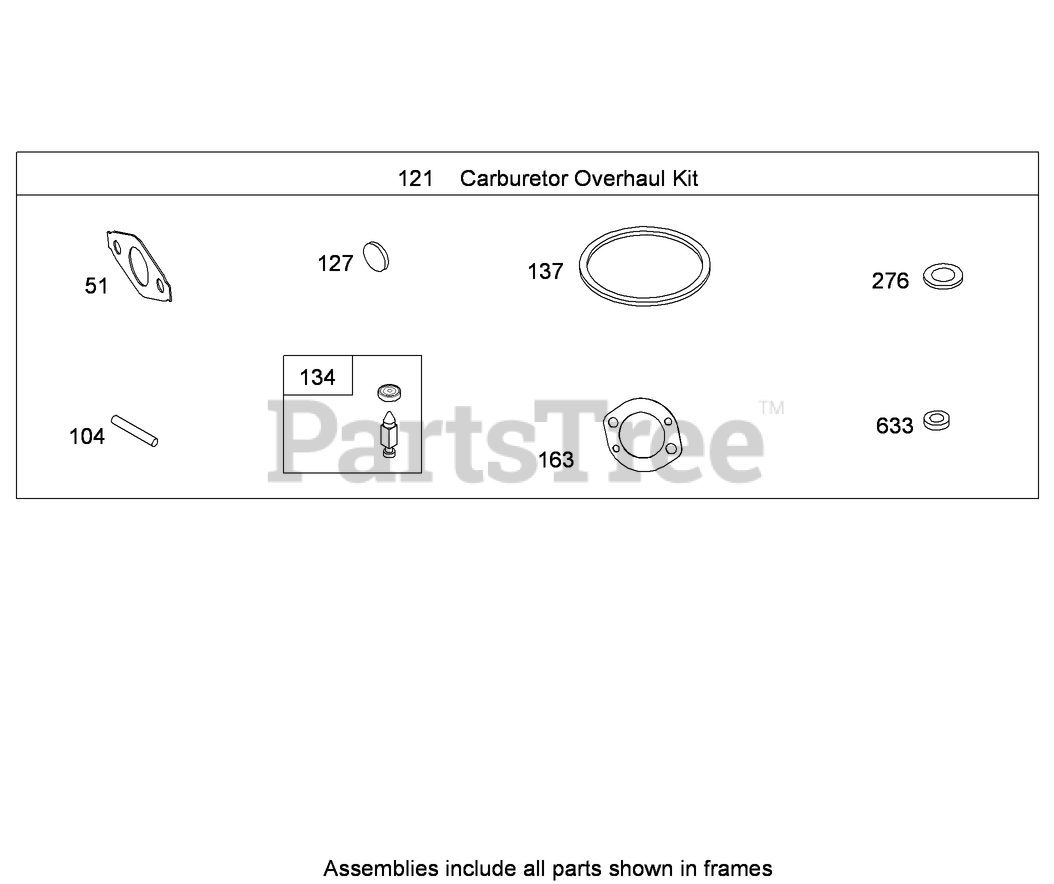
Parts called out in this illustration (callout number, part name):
51	Gasket-Intake
104	Pin-Hinge, Float
121	Lockwasher
127	Plug-Welch
134	Valve-Inlet (Includes Seat)
137	Gasket-Bowl, Float
163	Gasket-Air Cleaner
276	Washer-Sealing
633	Seal-Shaft, Choke Throttle
